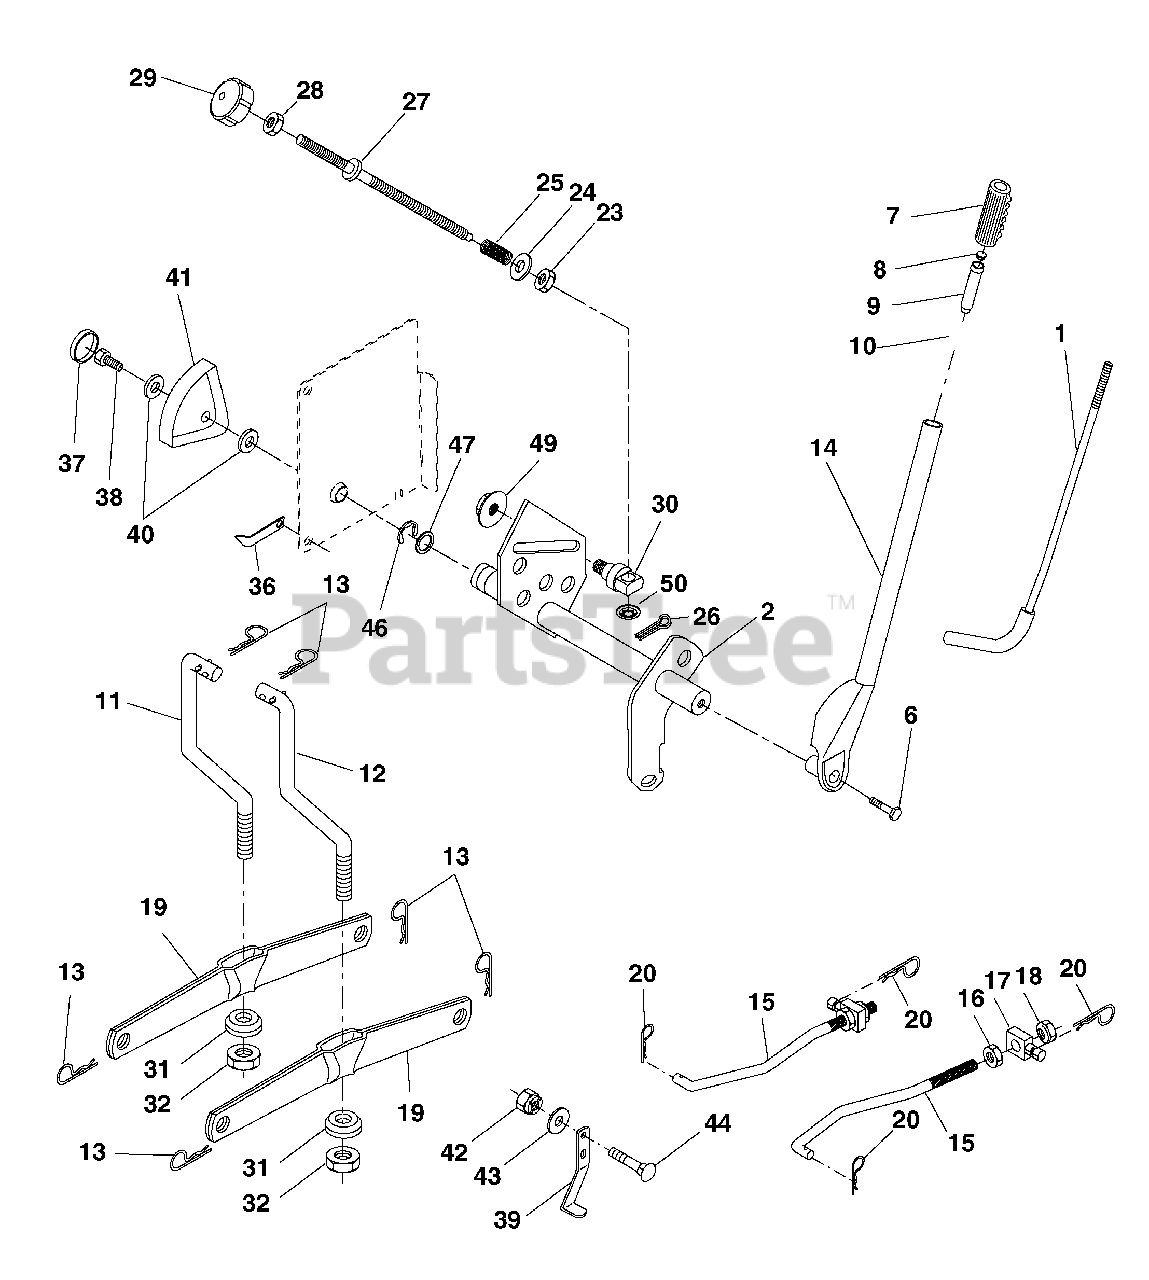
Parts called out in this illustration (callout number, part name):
1	Rod Assembly, Lever
2	Shaft Assembly, Lift
6	Bolt, Hex Head, Fin. 3/8-16 x 1-1/2
7	Grip Handle
8	Button Plunger Black
9	Plunger Lever Lift
10	Spring
11	Link, Lift, LH
12	Link, Lift, RH
13	Retainer Spring
14	Lever Assembly, Lift, RH
15	Link, Front
16	Nut, Hex, Jam 1/2-13 UNC
17	Trunnion
18	Nut Lock W/Wsh 1/2-13 Unc
19	Arm, Suspension, Rear
20	Retainer Spring
23	Nut Special
24	Washer 13/32 x 5/8 x 16 Ga.
25	Spring Compression
26	Pin Cotter
27	Rod Adj. Lift
28	Nut Hex Jam 3/8-16 Unc
29	Knob Inf. 3/8-16 Unc
30	Trunnion Infin Height
31	Bearing
32	Nut, Crownlock 3/8-24
36	Pointer Height Indicator
37	Plug Hole
38	Screw 5/16-18 x 1
39	Stop Over Center
40	Washer 11/32 x 1-1/2 10 Ga.
41	Scale Ind. Height
42	Nut, Crownlock 3/8-16 UNC
43	Washer 13/32 x 1 x 12 Ga.
44	Bolt, Carriage 3/8-16 x 1.00
46	E-Ring
47	Washer
49	Nut Hex Flange Lock
50	Nut Push
